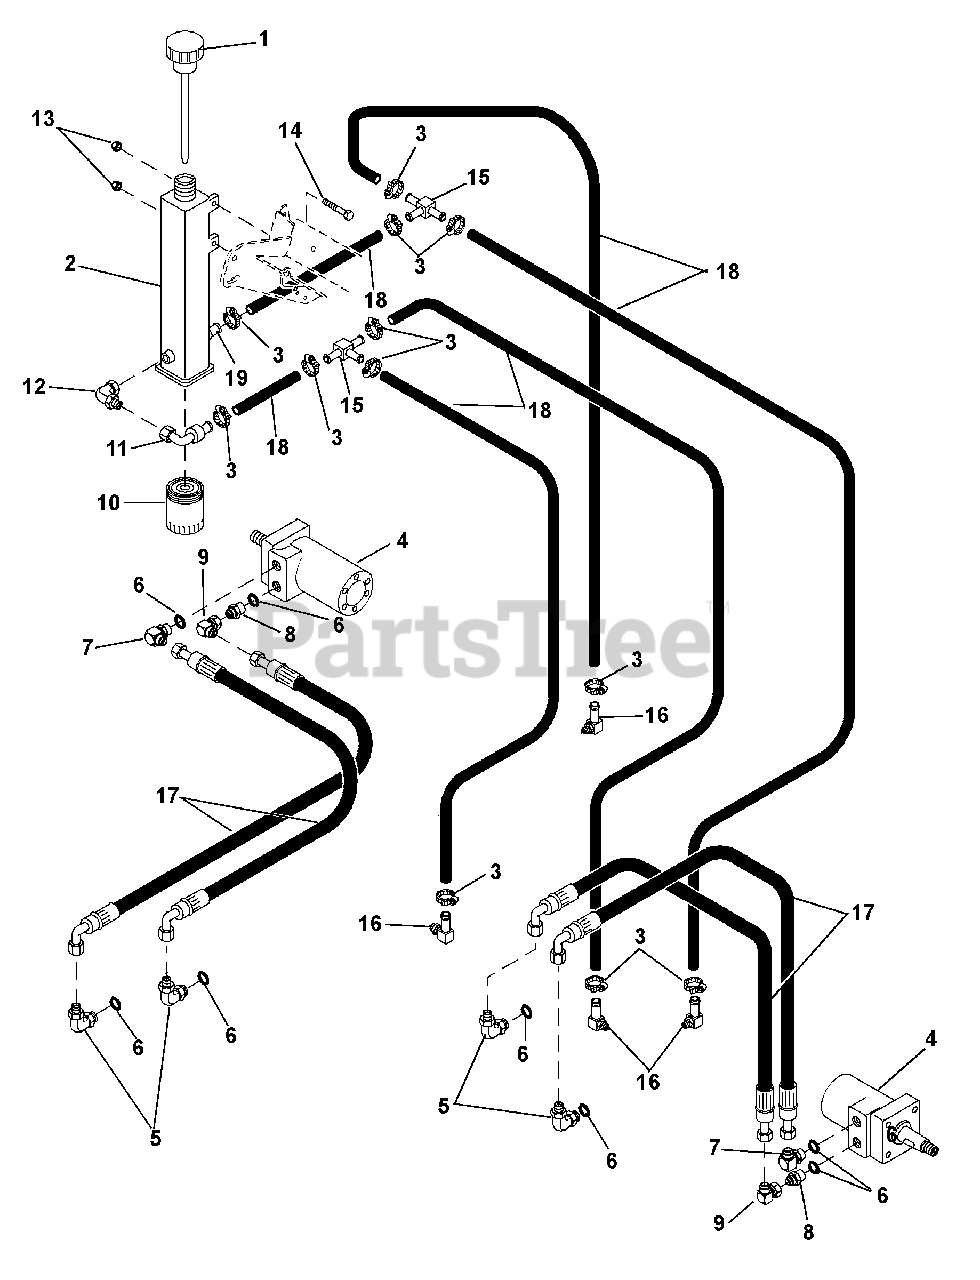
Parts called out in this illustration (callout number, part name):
1	Cap
2	Hydraulic Reservoir, Includes Decal
3	Hose Clamp
4	Wheel Motor
5	Fitting, Includes O-Ring
6	O-Ring, Included With Fitting
7	Adapter, 8MJ-10MB90
8	Adapter, Hydraulic 7/8 "0" to .3/4
9	Adapter, 3/4 FESW x 3/4 MJICX90
10	Element, Oil Filter
11	Elbow Fitting
12	Adapter 2503-6-6
13	Nut, Locking, Nylon M10-1.5
14	Bolt, Hex M10 x 1.5 x 20 Grade 5
15	Tee Fitting
16	Fitting, Adapter .562-18 Steel Thread
17	Hose, High Pressure
18	Hose, Return, 25 Ft Black - Cut to Length
19	Adapter, Straight Fitting
